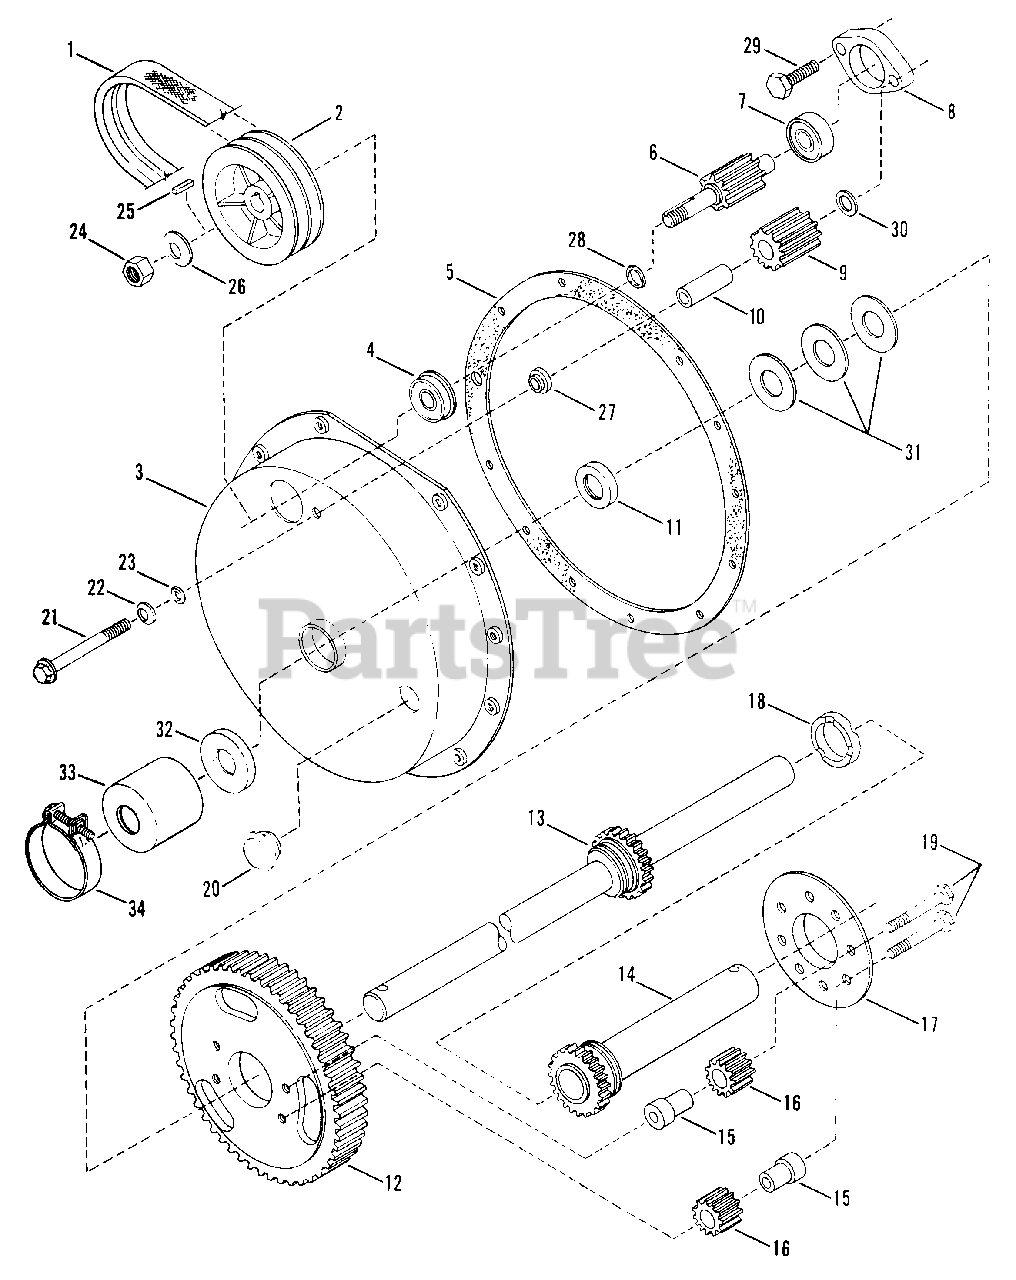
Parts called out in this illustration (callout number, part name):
1	BELT, Wheel Drive
2	PULLEY, Wheel Drive Belt
3	COVER, Differential
4	BEARING
5	GASKET, Differential Cover
6	PINION GEAR & SHAFT
7	BEARING
8	HOLDER, Bearing
9	GEAR, 11 Teeth, 10 Pitch
11	SEAL, Differential
12	GEAR, 63 Teeth, 10 Pitch
13	AXLE, Long
14	AXLE, Short
15	SPACER, Pinion
16	PINION GEAR, Differential
17	PLATE, Differential
18	SPACER, Differential (1.25" ID x .425 Wide)
19	SCREW, 5/16-24 x 1-5/8" Hex Head Cap, Special Lock
20	PLUG, 3/4"
21	SCREW, 5/16-24 x 2-1/2" Hex Head Cap
22	WASHER, Belleville
23	O-RING, 5/16"
24	NUT, 7/16-20 Hex, Top-Lock
25	KEY, Square, 1/8 x 1/2" L.
26	WASHER, Belleville, 7/16"
28	O-RING, 15/32"
29	SCREW, 5/16-24 x 1" Hex Head Cap
30	WASHER, Shim, 5/16"
31	WASHER, Thrust
32	SEAL, 3/4"
33	CAP
34	CLAMP, 1-5/8"
